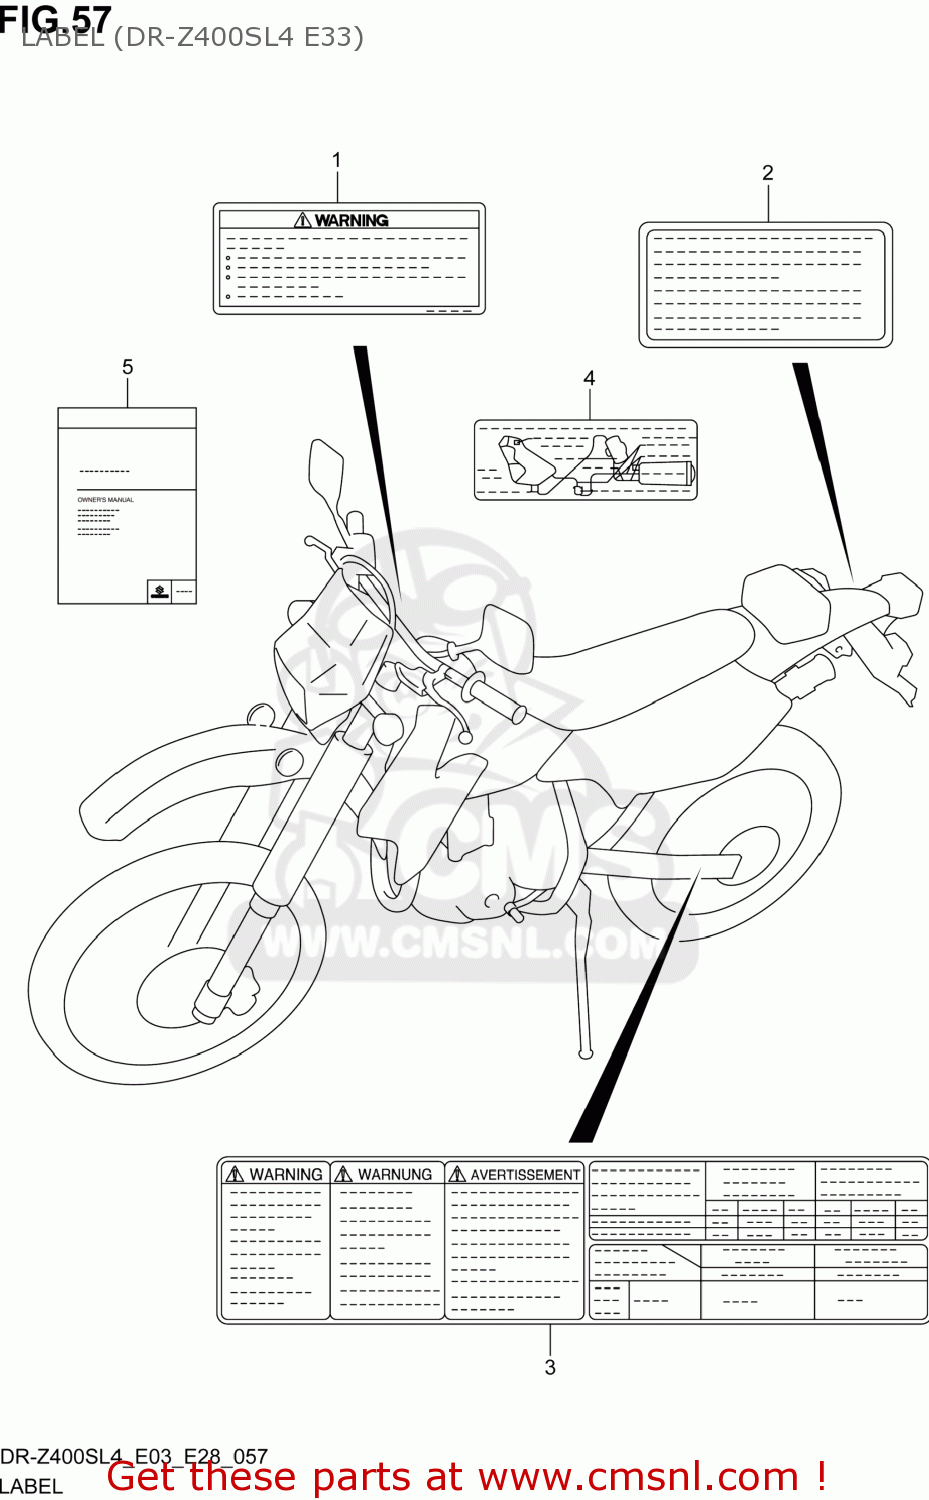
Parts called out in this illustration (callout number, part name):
1	LABEL,GENERAL WARNING
2	LABEL,MANUAL NOTICE
3	LABEL,TIRE INFORMATION
4	LABEL,VACUUM HOSE ROUTING
5	MANUAL,OWNER'S
